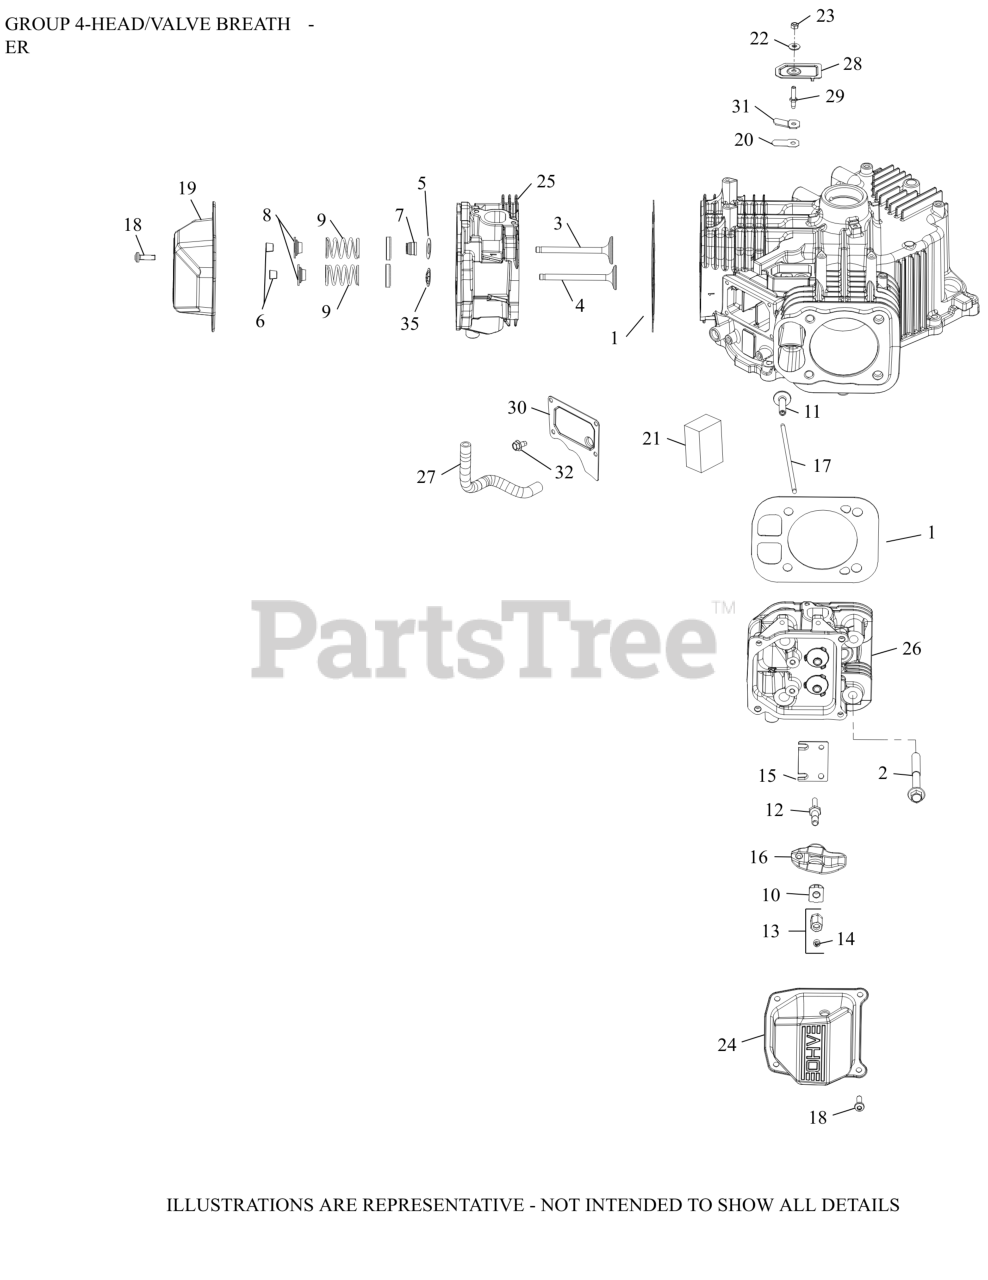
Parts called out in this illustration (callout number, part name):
1	KIT, CYLINDER HEAD GASKET
2	SCREW, FLG M10X1.5X90
3	VALVE, INTAKE
3	VALVE, INTAKE (.25) - (#2401702S)
4	VALVE, EXHAUST
4	VALVE, EXHAUST (.25)
5	SPACER (.010")
6	KIT, RETAINER
7	SEAL, VALVE BAND
8	CAP, VALVE SPRING
9	SPRING VALVE
10	PIVOT, ROCKER ARM
12	STUD, ROCKER
13	HEX NUT ASSEMBLY
14	SCREW, SET
15	PLATE, GUIDE
16	ARM, ROCKER
17	ROD, PUSH
18	SCREW, PAN HEAD
19	COVER, ROCKER STAMPED STEEL
20	REED, BREATHER
21	FILTER, BREATHER
22	WASHER, SEALING
23	NUT, LOCK M5X.8
24	COVER, ROCKER STAMPED STEEL
25	HEAD, ASSY CYL (#1)-USE 32 755 29-S
26	HEAD, ASSY CYL (#2)-(#3275530S)
27	HOSE, BREATHER
28	COVER, BREATHER REED
30	COVER, BREATHER MEDIA
31	RETAINER, REED
32	SCREW, THREAD FORMING
35	RETAINER, VALVE GUIDE (KM)
